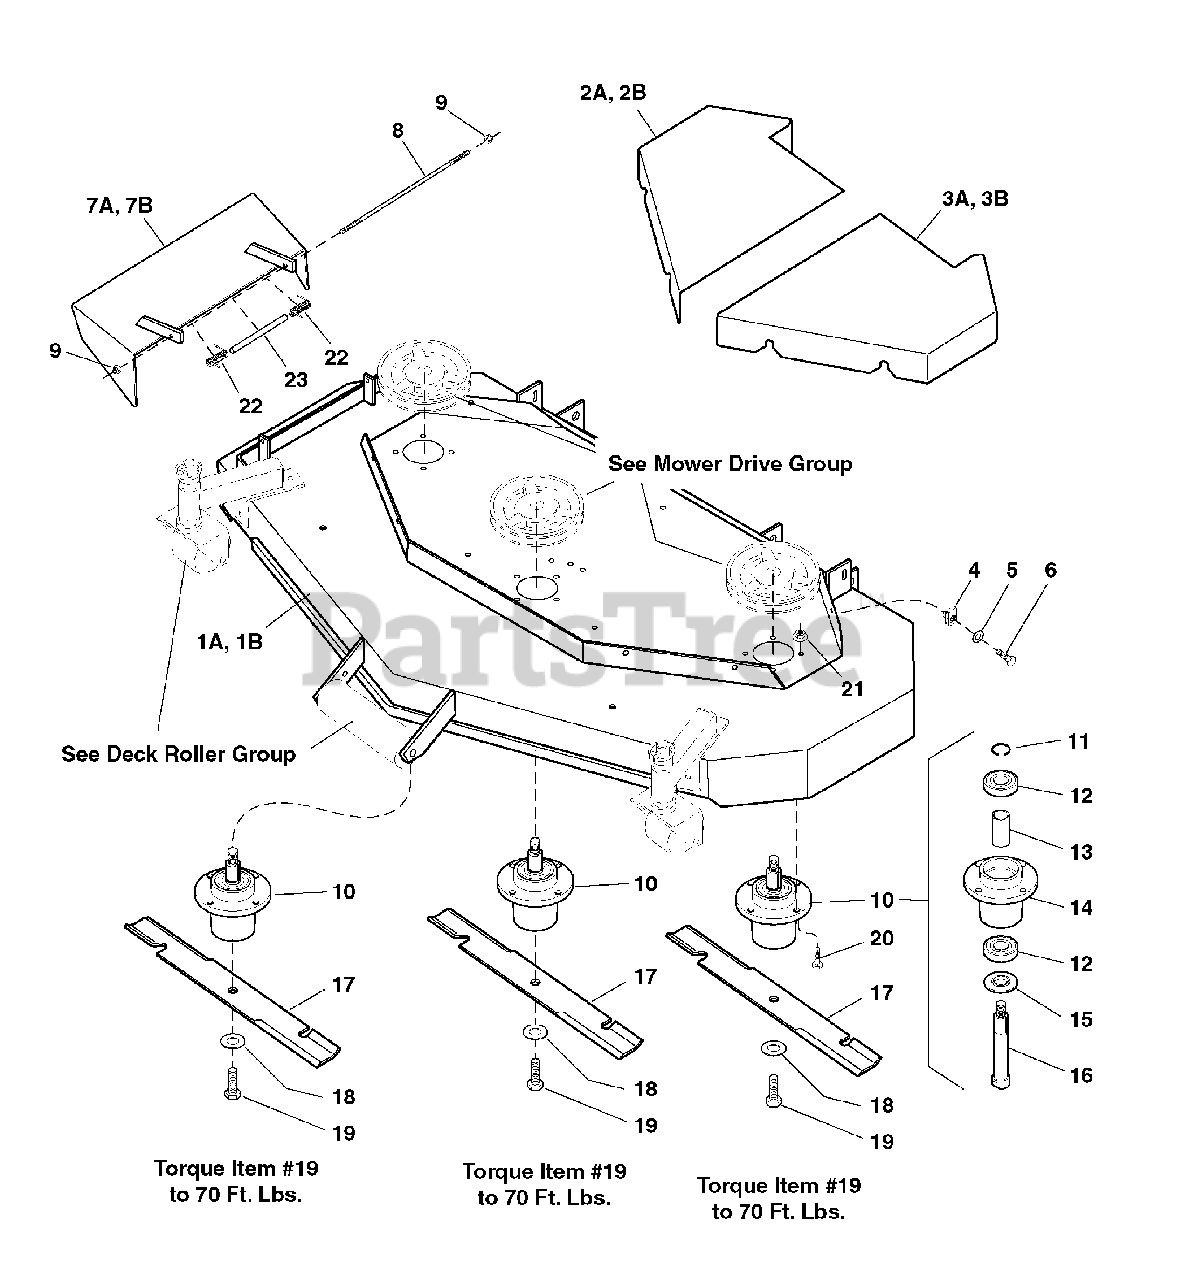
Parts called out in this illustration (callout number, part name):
1A	61" MOWER HOUSING (S/N 101-615)
1B	61" MOWER HOUSING (S/N 616 & up)
2A	SPINDLE COVER-RH (S/N 101-615)
2B	SPINDLE COVER-RH (S/N 616 & up)
3A	SPINDLE COVER-LH (S/N 101-615)
3B	SPINDLE COVER-LH (S/N 616 & up)
4	BODY CLIP, 5/16-18
5	WASHER, 5/16
6	CAPSCREW, Hex Hd, 5/16-18 x 3/4
7A	DISCHARGE CHUTE (S/N 101-615)
7B	DISCHARGE CHUTE (S/N 616 & up)
9	NUT, Hex, Nylon Lock, 5/16-18
10	SPINDLE ASSEMBLY, Complete (includes Ref 11-16)
12	BEARING, Roller
13	SPACER, Bearing
14	SPINDLE HOUSING
15	TRASH SHIELD
16	SPINDLE SHAFT
17	MOWER BLADE
18	WASHER, USS, 5/8
19	CAPSCREW, Hex Hd, 5/8-11 x 1-3/4
20	CAPSCREW, Hex Hd, 5/16-18 x 1-1/8
21	NUT, Hex, Serrated Flange, 5/16-18
22	SPRING, Torsion
23	SPRING SPACER
